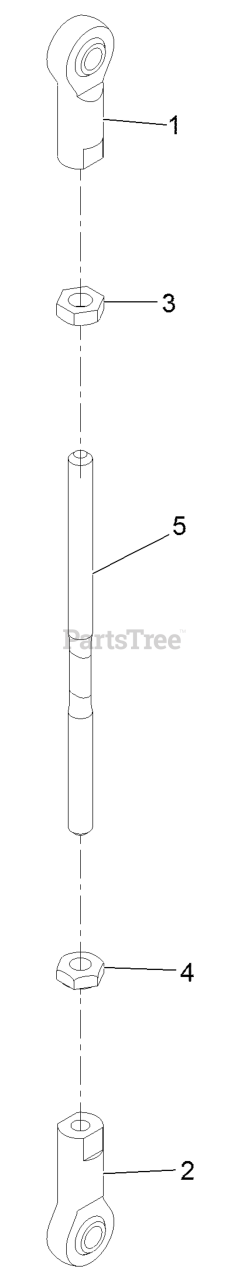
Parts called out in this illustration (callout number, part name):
1	ROD END-BALL JOINT
2	JOINT-BALL, LH
3	NUT-JAM
4	NUT-JAM
